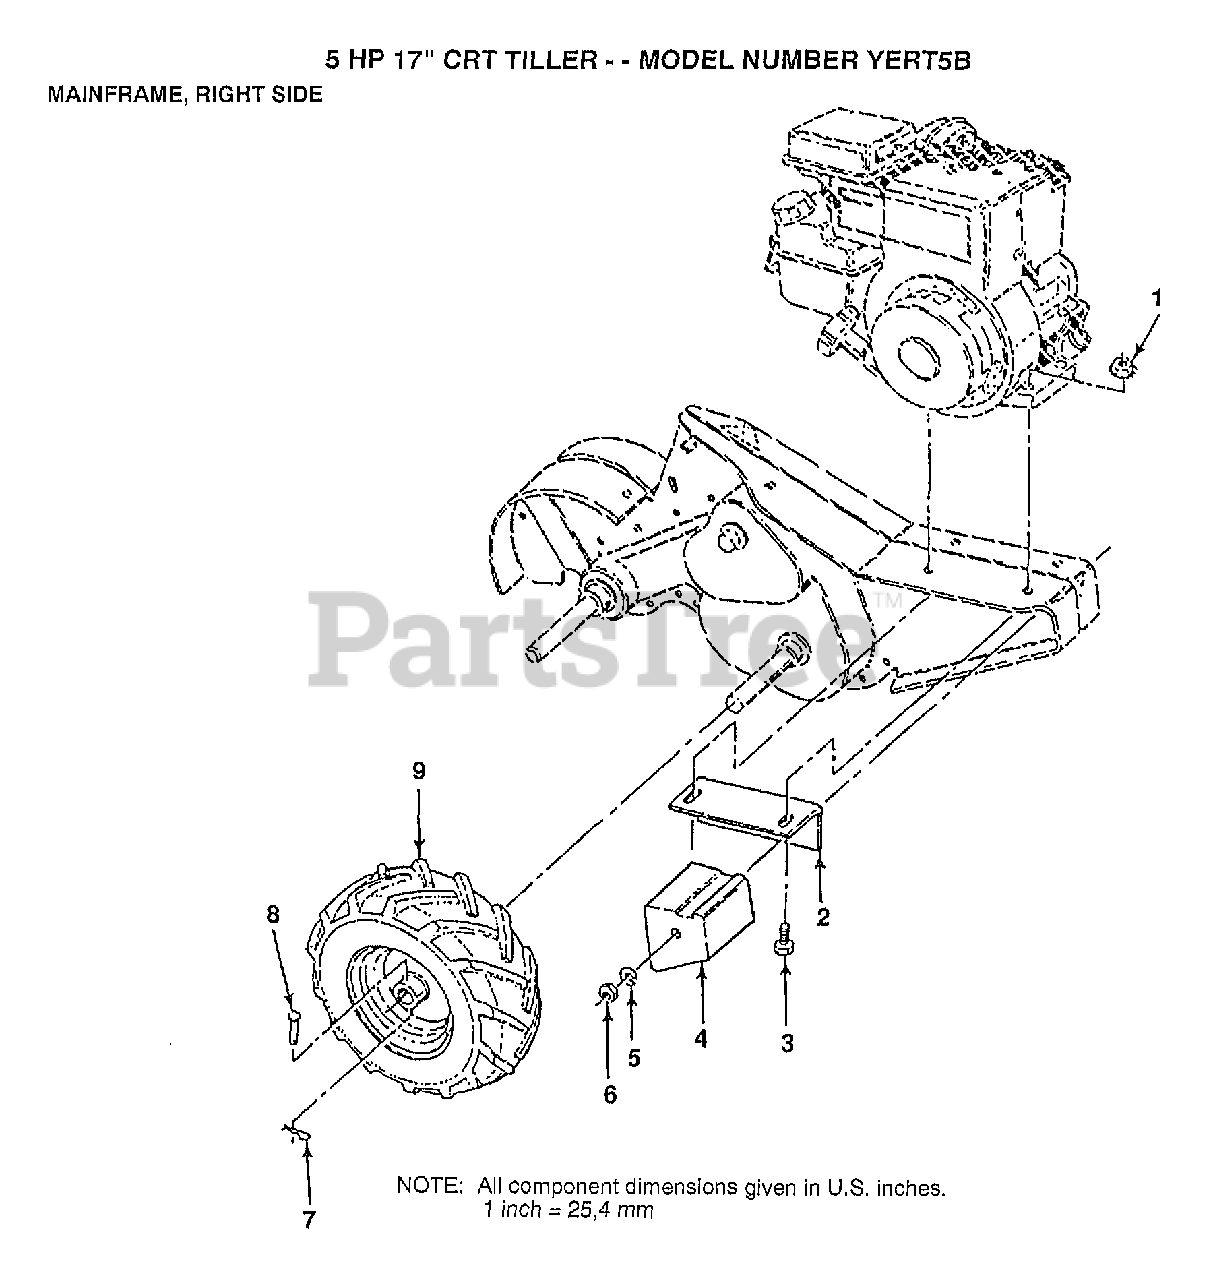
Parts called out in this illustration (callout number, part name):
2	BRACKET RH CRT
3	BOLT.HEX.5/16-1.5
4	COUNTERWEIGHT CRT
5	LOCKWASHER
6	NUT.HEX.3/8-16UNC
7	RETAINER M
8	RIVET.DRILL.1.75
9	TIRE.CHV.13X5.0-6
